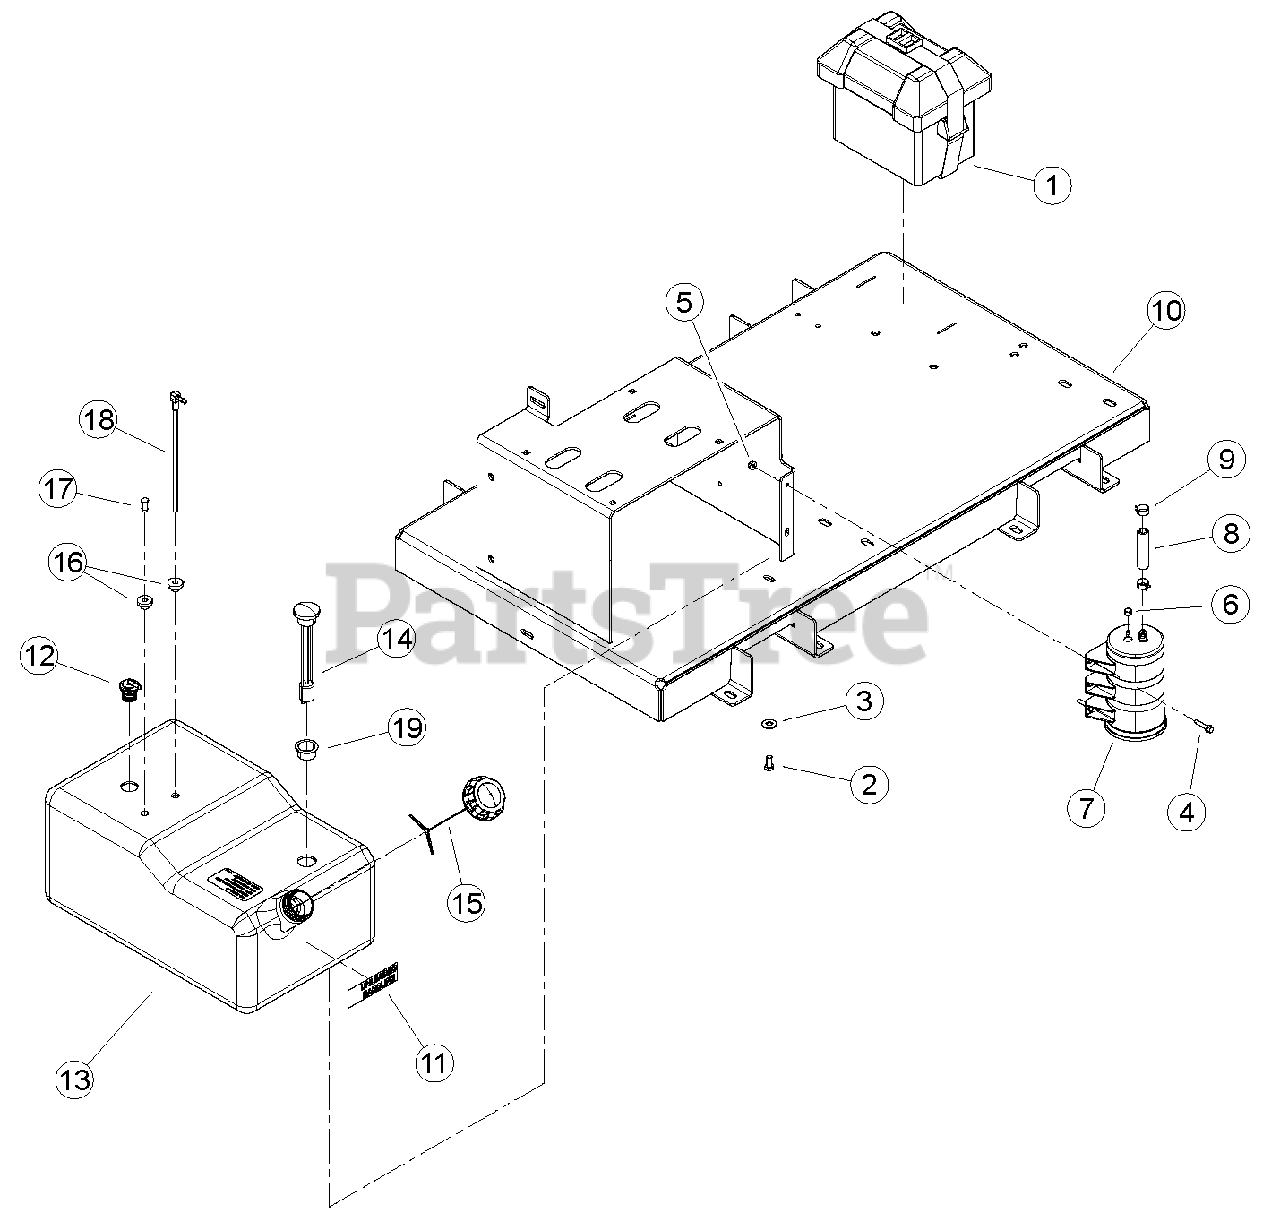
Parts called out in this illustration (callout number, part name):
1	BOX, SMALL BATTERY
2	BOLT, 3/8 X 3/4 GR5 HEX CAPSCW ZP
3	WASHER, 3/8" FLAT ZP
4	BOLT, 1/4 X 1-1/4 FLANGE NC
5	NUT, 1/4-20 NYLOCK-FLANGE
6	CLAMP, 15/32 SPRING
7	CARBON CANISTER, 1000CC
8	HOSE, 1/2 X 3" FUEL LINE
9	CLAMP, SPRING 1/2" ID HOSE
10	WELDMENT, BASE DL12720
11	DECAL, UNLEADED GASOLINE
12	VALVE, ROLL OVER
13	TANK, ROTOMOLDED FUEL
14	GAUGE, FUEL LEVEL KELCH 100
15	CAP, NON-VENTED EPA/CARB APPROVED
16	GROMMET, TANK FITTING
17	PLUG, TANK VENT
18	FITTING, TANK FUEL PICK-UP TUBE
19	GROMMET, KELCH 100 GAUGE
